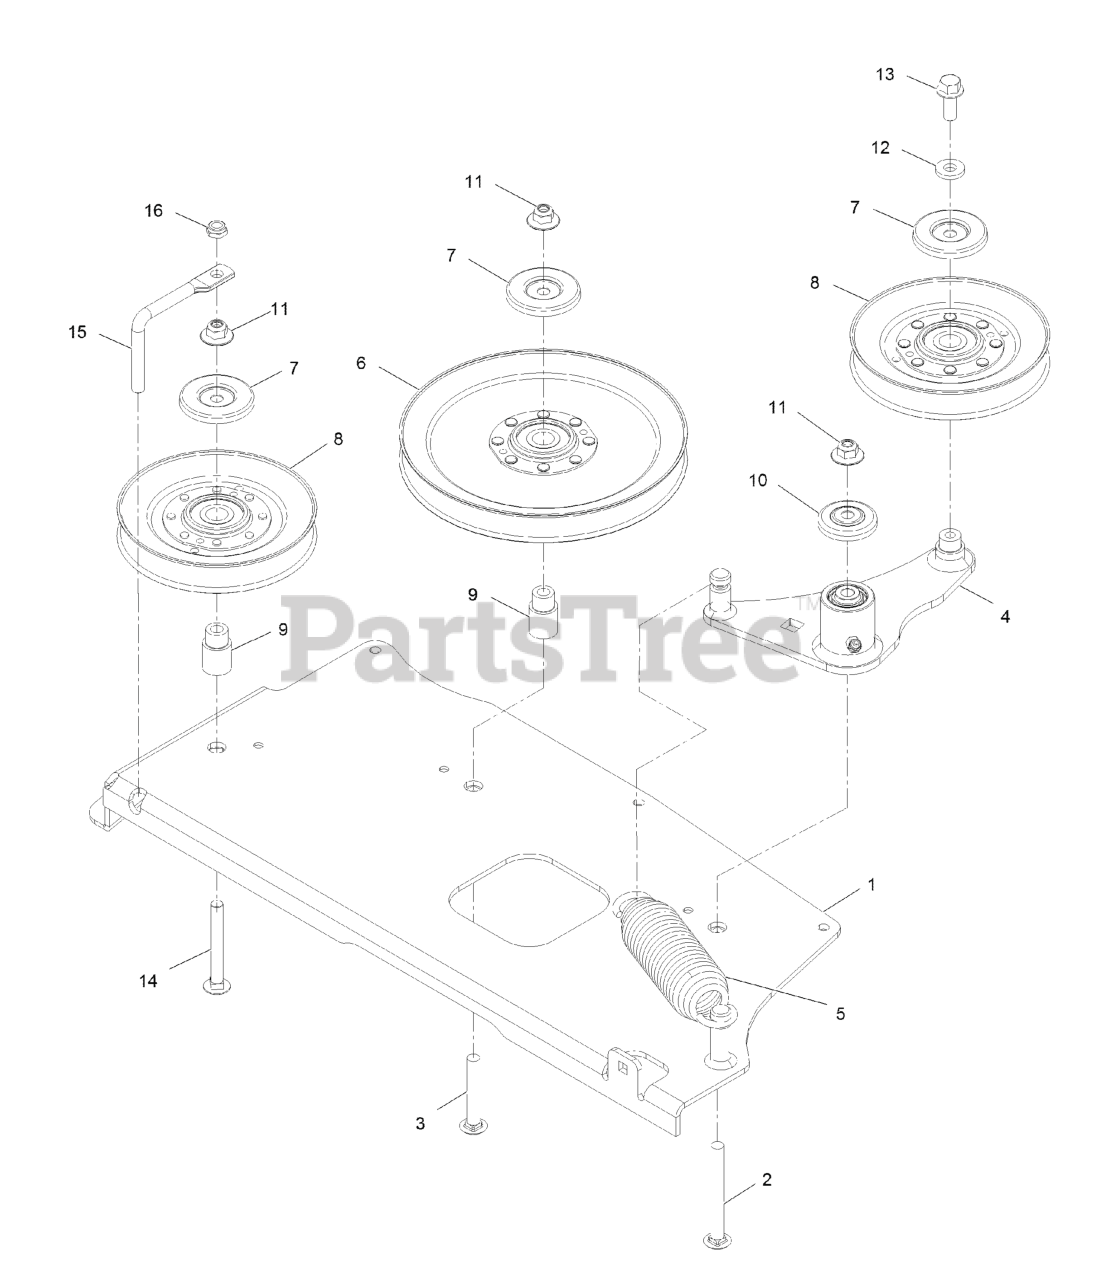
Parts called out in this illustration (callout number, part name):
1	MOUNT-IDLER
2	BOLT-SHOULDER, CARRIAGE 3/8-16 X 3 1/2
3	SCREW-CARR
3	RING-SNAP
4	IDLER ARM ASM
4	BEARING-SPHERICAL
5	SPRING-EXTENSION
6	SEAL-LIP, DOUBLE
6	IDLER-V
7	SEAL-LIP, SINGLE
7	SHIELD-DUST
8	IDLER V
9	STANDOFF-IDLER
10	GUARD-TOP
11	Nut-Nyloc 3/8-16 Flg
13	SCREW-HHF
14	SCREW-CARR
15	GUIDE-BELT
